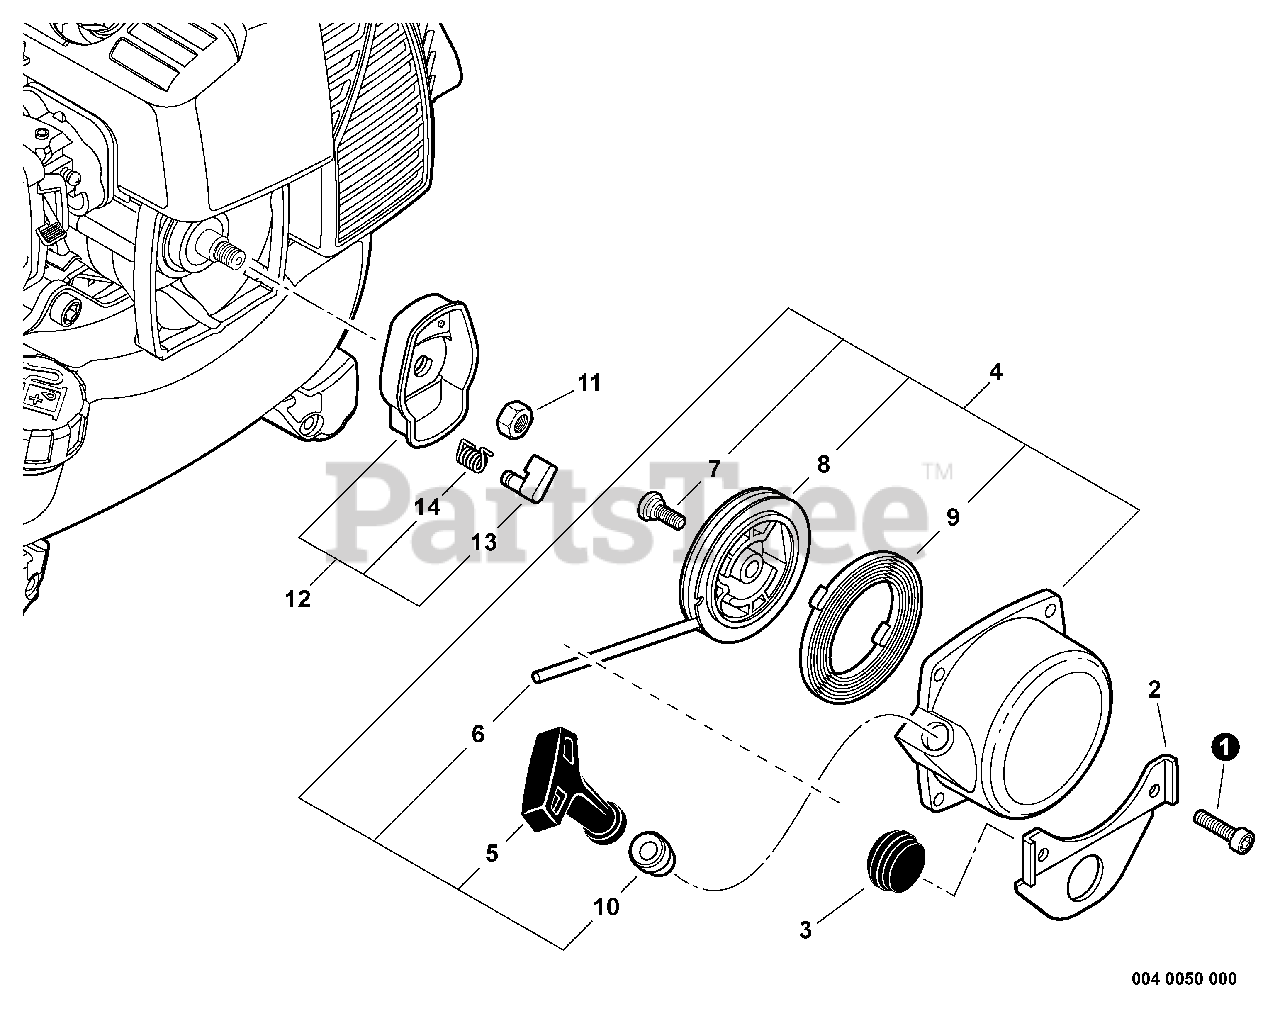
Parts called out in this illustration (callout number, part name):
1	SCREW - 4X16
2	BRACKET, FUEL TANK
3	CUSHION
4	STARTER ASSY
5	GRIP, STARTER
6	ROPE, STARTER - 3X1000
8	REEL, ROPE
9	SPRING, REWIND
10	GUIDE, ROPE
12	STARTER PAWL ASSY
13	PAWL, STARTER - BLACK
14	SPRING, RETURN
